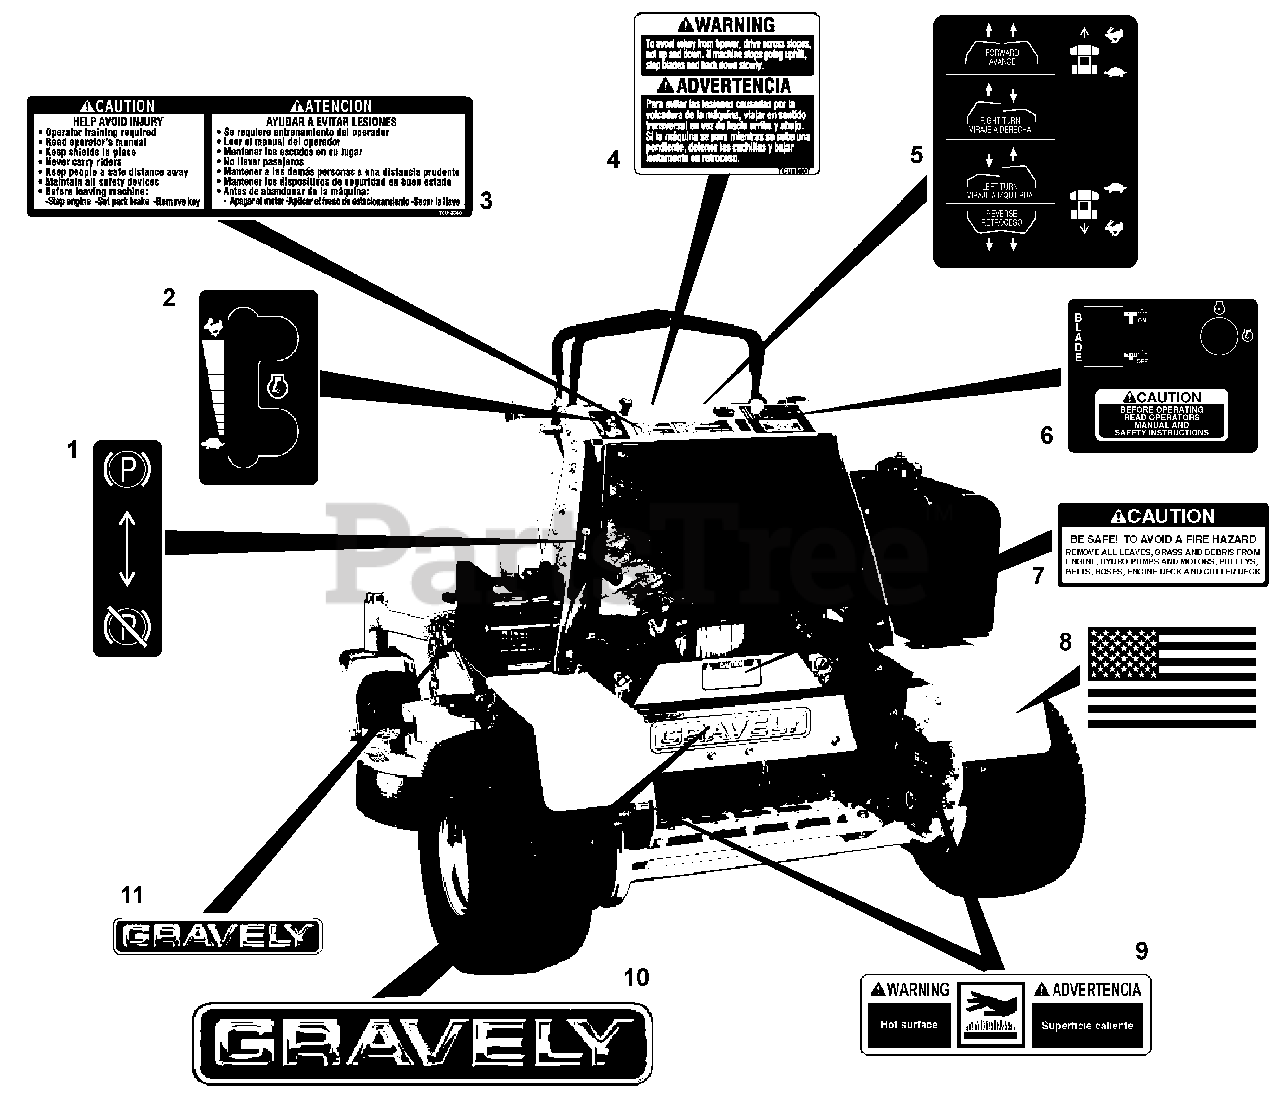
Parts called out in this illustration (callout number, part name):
1	Decal, Park BrakeDirection
2	Decal, Throttle
3	Decal, General Caution
4	Decal, Warning -Slope
5	Decal, Directional Control
6	Decal, PTO and Key Ignition
7	Decal, Debris
8	Decal, American Flag
9	Decal, Warning, Hot Surface
10	Decal, 15" Gravely Logo
11	Decal, Gravely Logo
